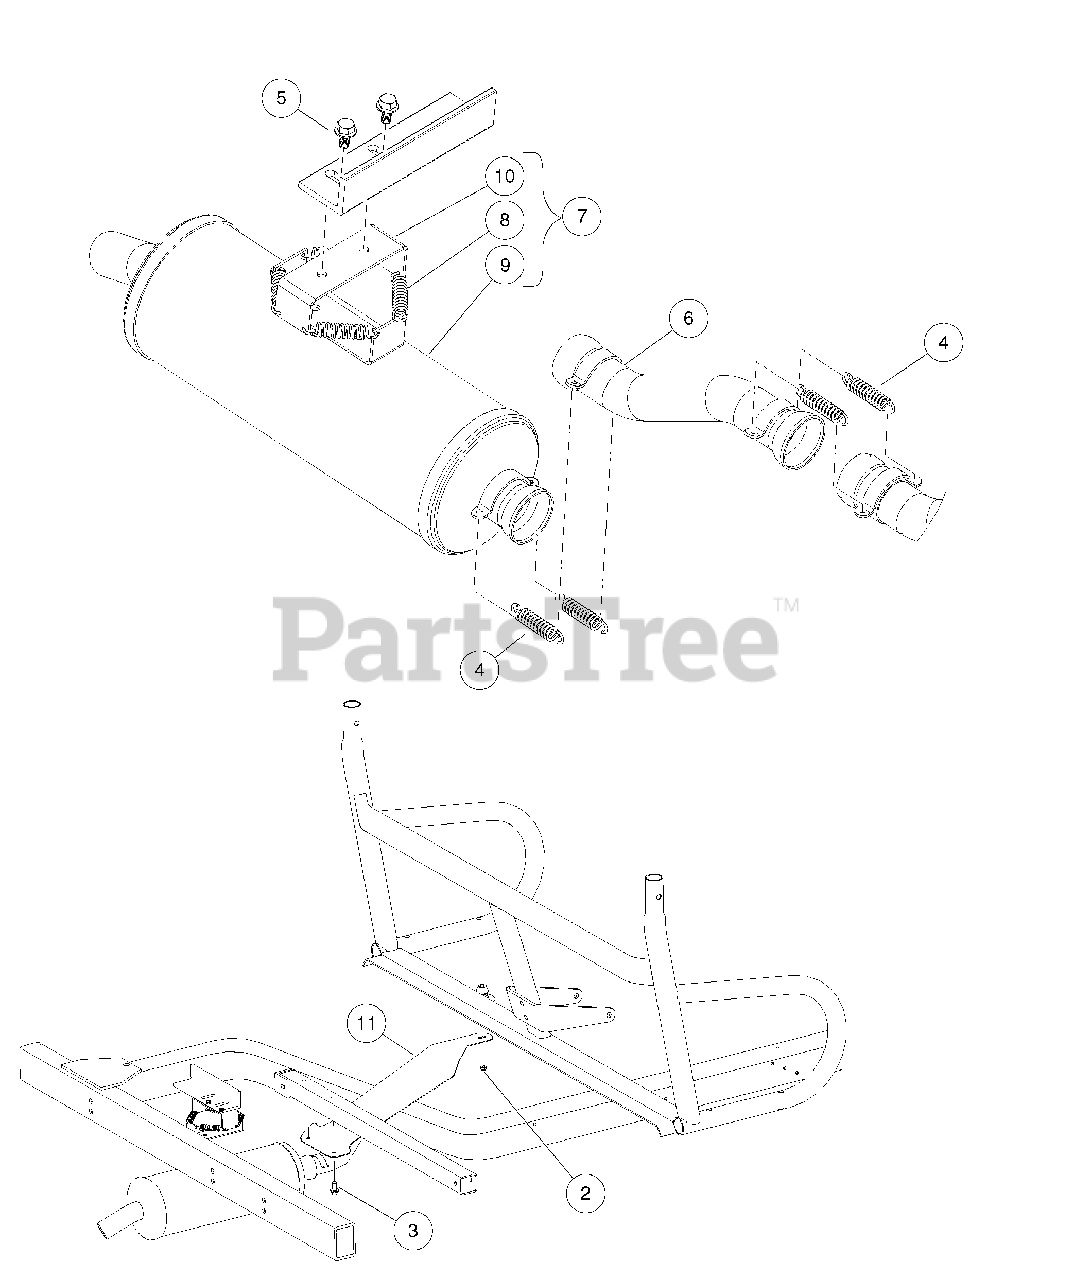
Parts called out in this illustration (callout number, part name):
1	Instl, Exhaust, AWD
2	Locknut, M6-1.00 Nylon Insert
3	M8-1.25x20 Taptite
4	Spring, Exhaust
5	Bolt Flanged Head, M8 X1.25x 16 with Loctite
6	Pipe, Exhaust, Int, Offset
7	Asm, Muffler, AWD Homologation
8	Spring, Exhaust
9	Muffler
10	Bracket, Muffler
11	Shield, Exhaust, Clearance
